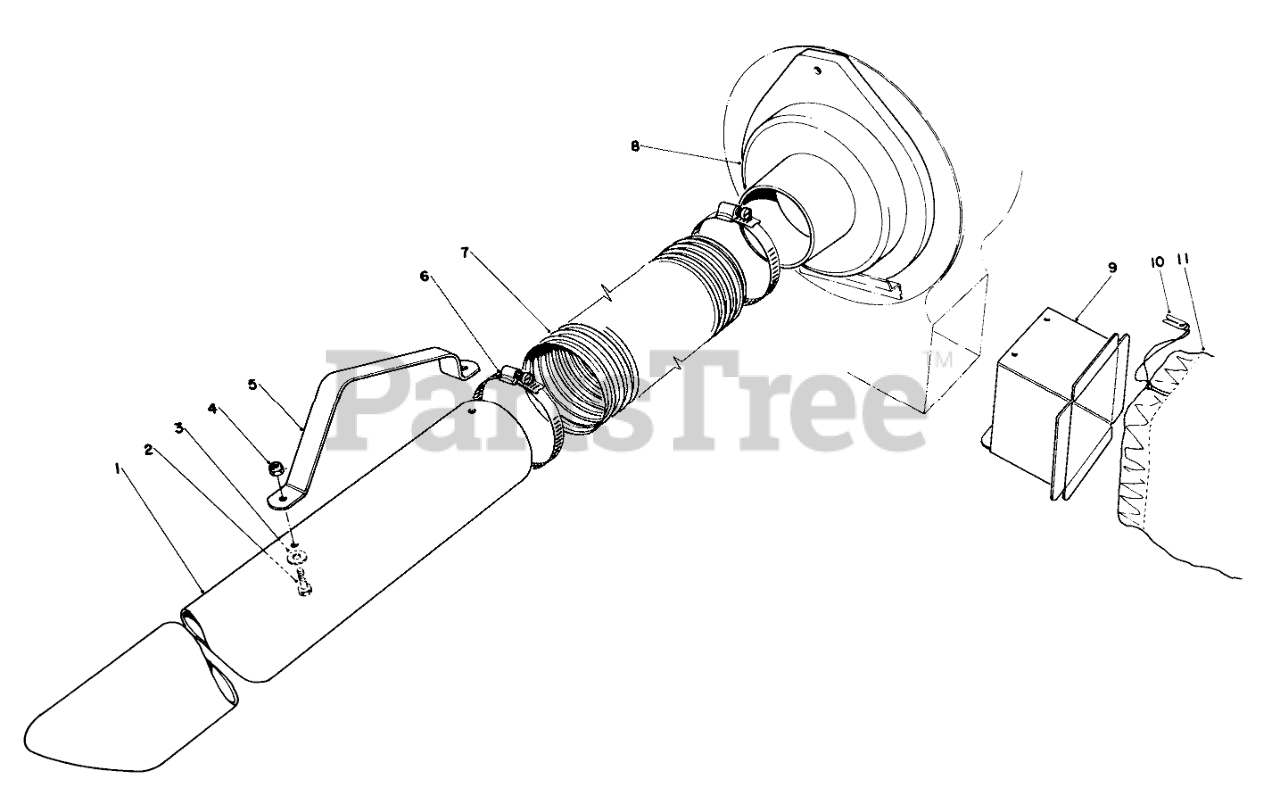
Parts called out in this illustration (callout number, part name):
1	NOZZLE
2	SCREW-HH
3	SPECIAL WASHER
4	NUT-KEPS
5	NOZZLE HANDLE
6	CLAMP
7	VACUUM HOSE
8	ADAPTOR HOSE TO HSG
9	HOUSING WA BLOWER BAG
10	BAG CORD FASTENER
11	Bag
